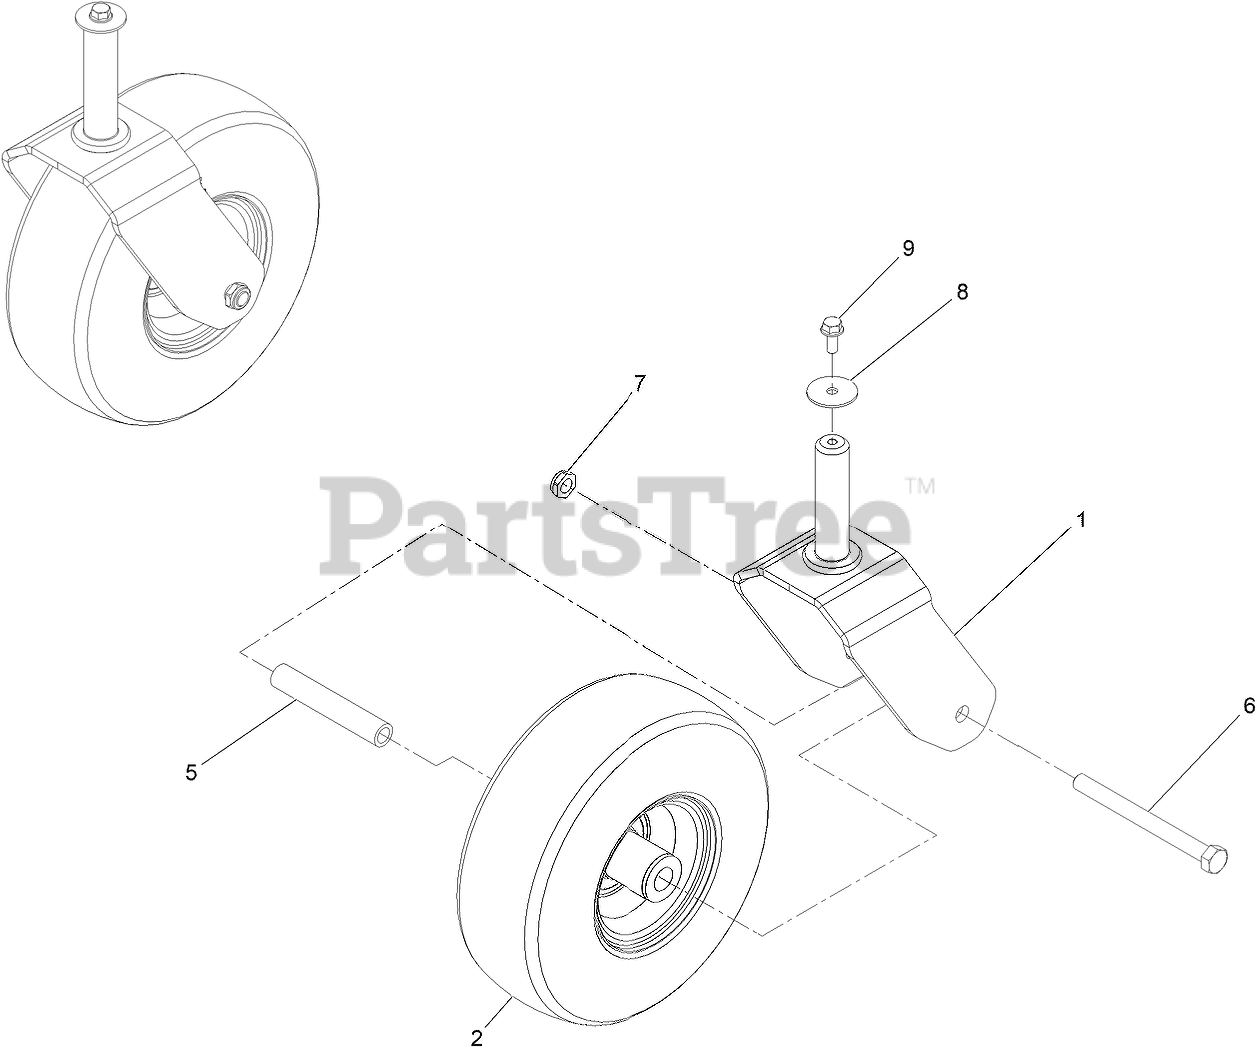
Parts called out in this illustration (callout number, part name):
2	TIRE ASM
5	BUSHING-SPANNER
6	SCREW-HH
7	NUT-HEX
8	WASHER-FLAT
9	SCREW-HHF
